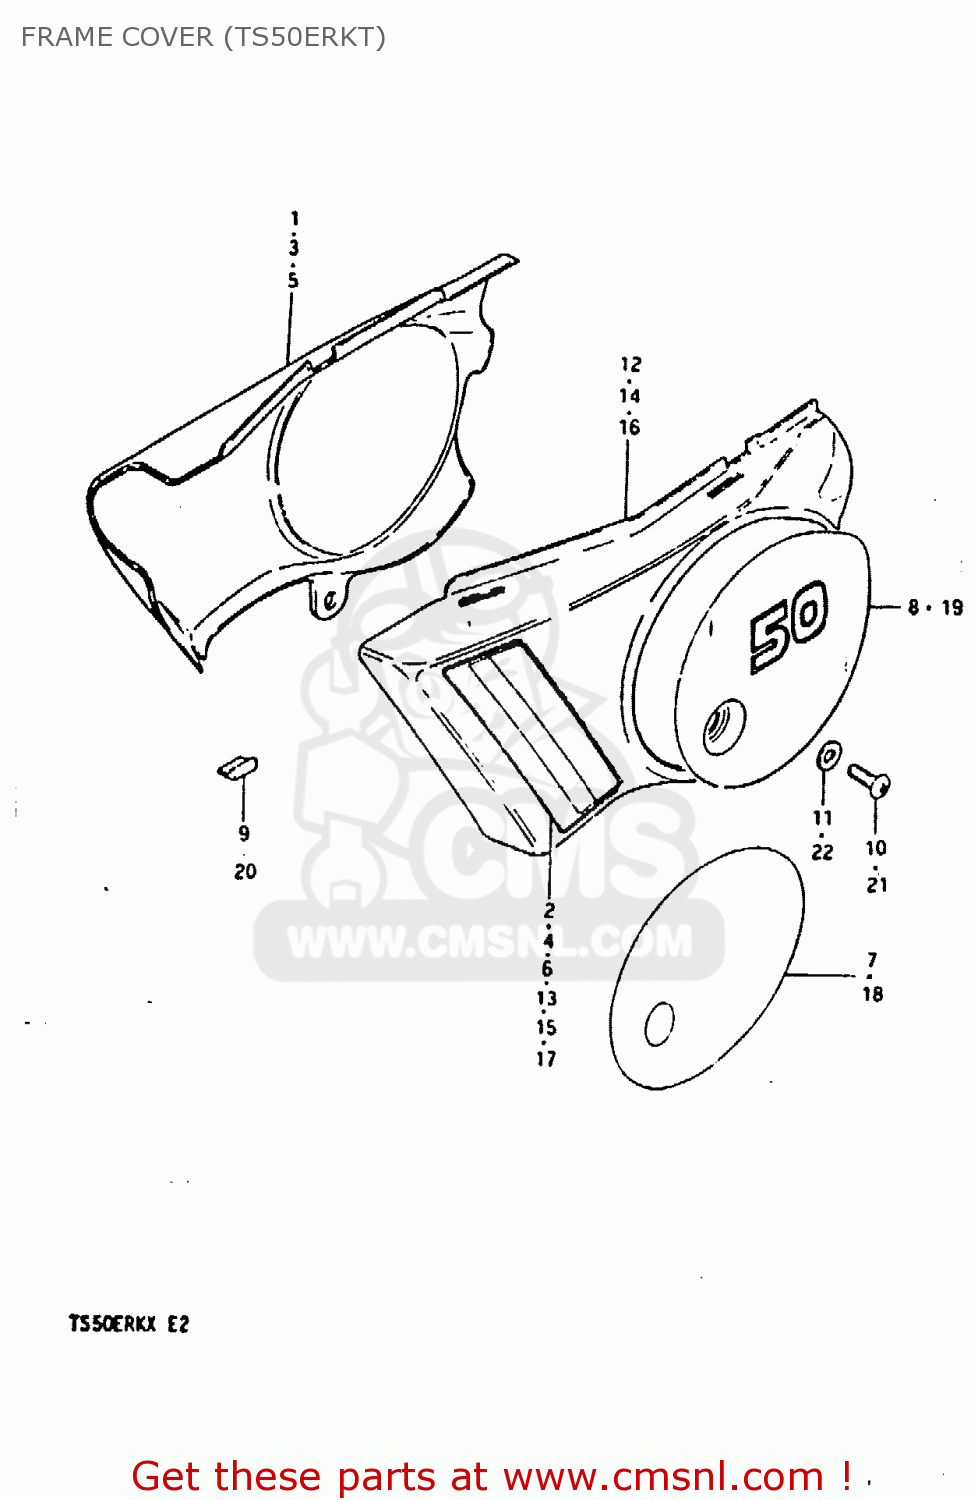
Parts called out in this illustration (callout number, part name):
1	COVER, FRAME RH (RED)
2	TAPE, STRIPING RH
3	COVER,FRAME RH
4	TAPE, STRIPING RH
5	COVER,FRAME RH
6	TAPE, STRIPING RH
7	EMBLEM, RH
9	CUSHION,FRAME COVER
10	SCREW 6X12
11	WASHER
12	COVER, FRAME LH (RED)
13	TAPE, STRIPING LH
14	COVER, FRAME LH (BLUE)
15	TAPE, STRIPING LH
16	COVER, FRAME LH (WHITE)
17	TAPE, STRIPING LH
18	EMBLEM, LH
20	CUSHION,FRAME COVER
21	SCREW
22	WASHER
